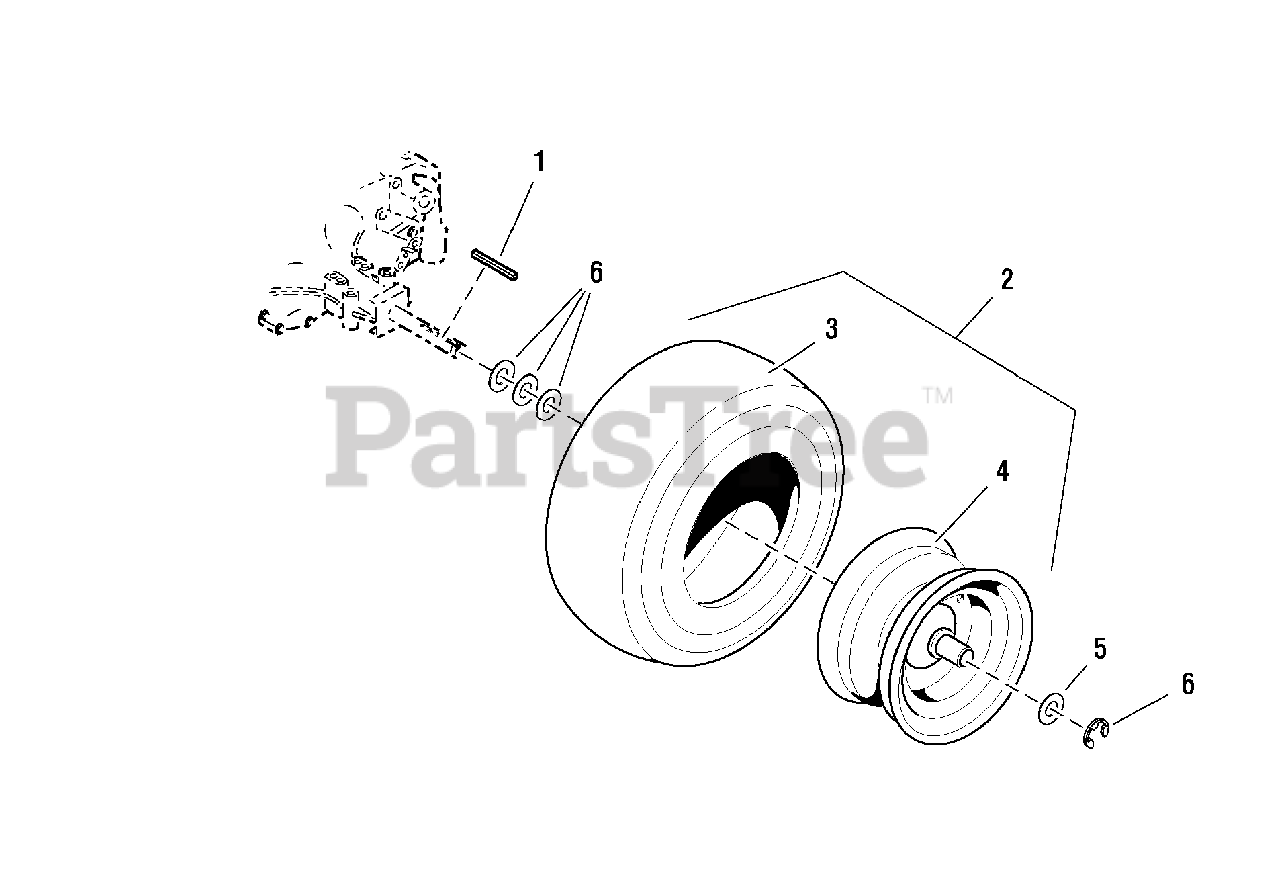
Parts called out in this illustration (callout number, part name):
2	WHEEL & TIRE ASSEMBLY, 16 x 6.5 x 8, Complete (Includes Ref. No. 3 & 4)
3	TIRE, 16. x 6.5 x 8
4	WHEEL ASSEMBLY, 8 x 5.38
